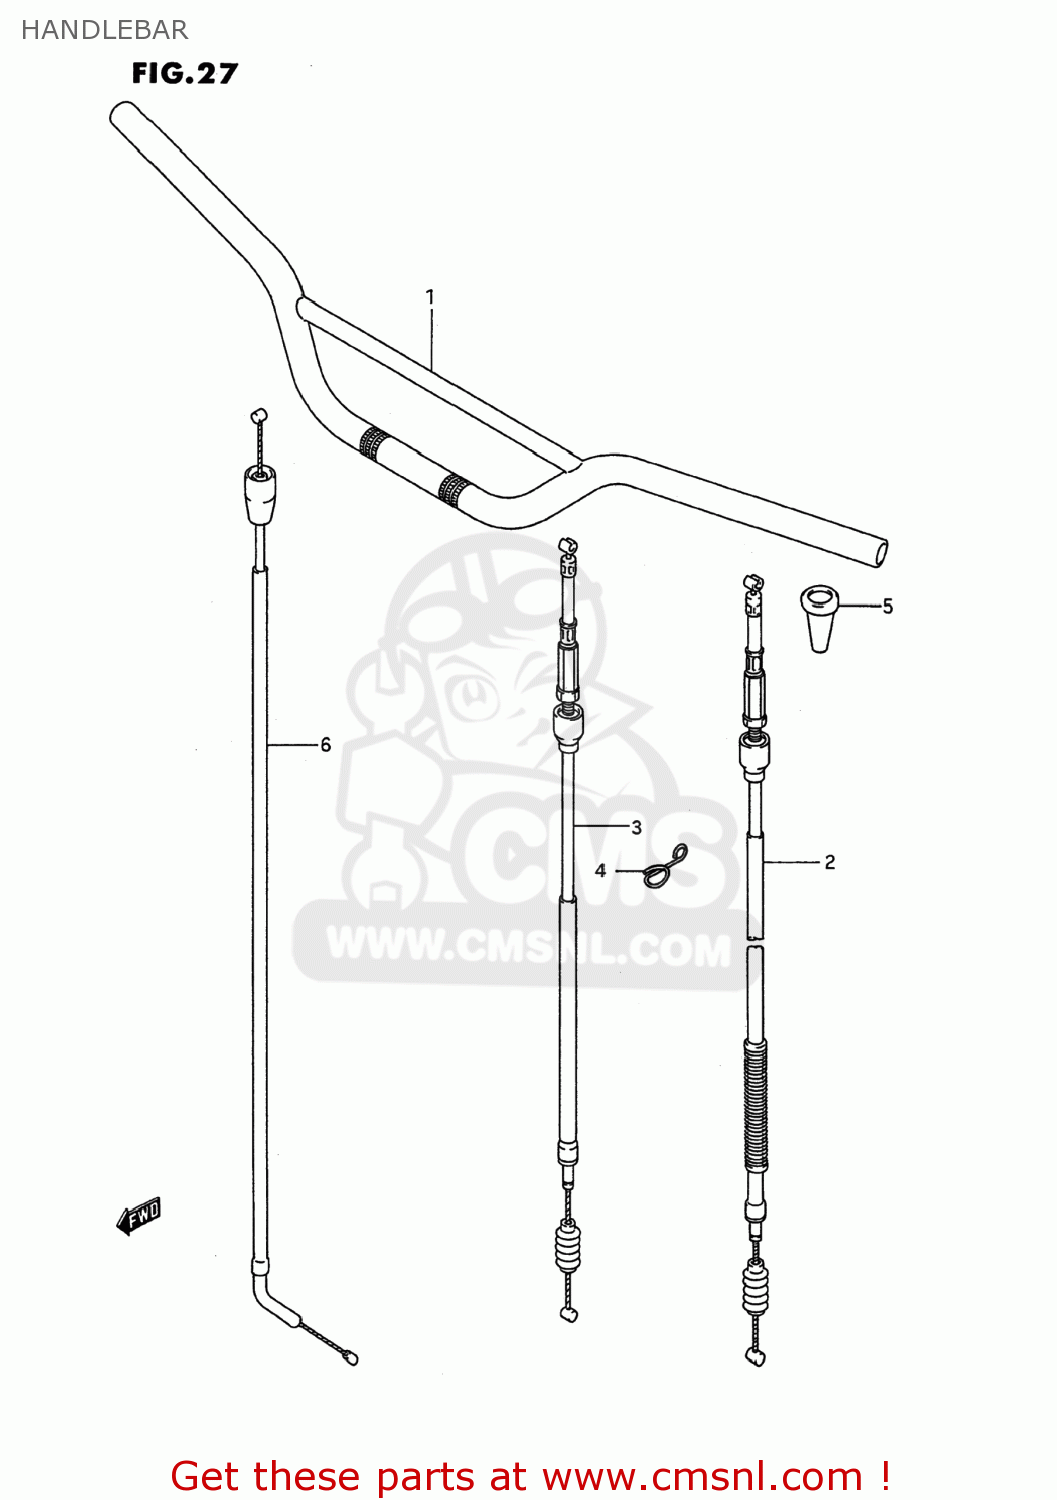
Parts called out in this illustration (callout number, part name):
1	HANDLEBAR
2	CABLE ASSY,CLUTCH
3	CABLE ASSEMBLY,CLUTCH
4	CLAMP,CLUTCH CABLE NO
5	BOOT,CLUTCH CABLE
6	CABLE ASSY,THROTTLE
